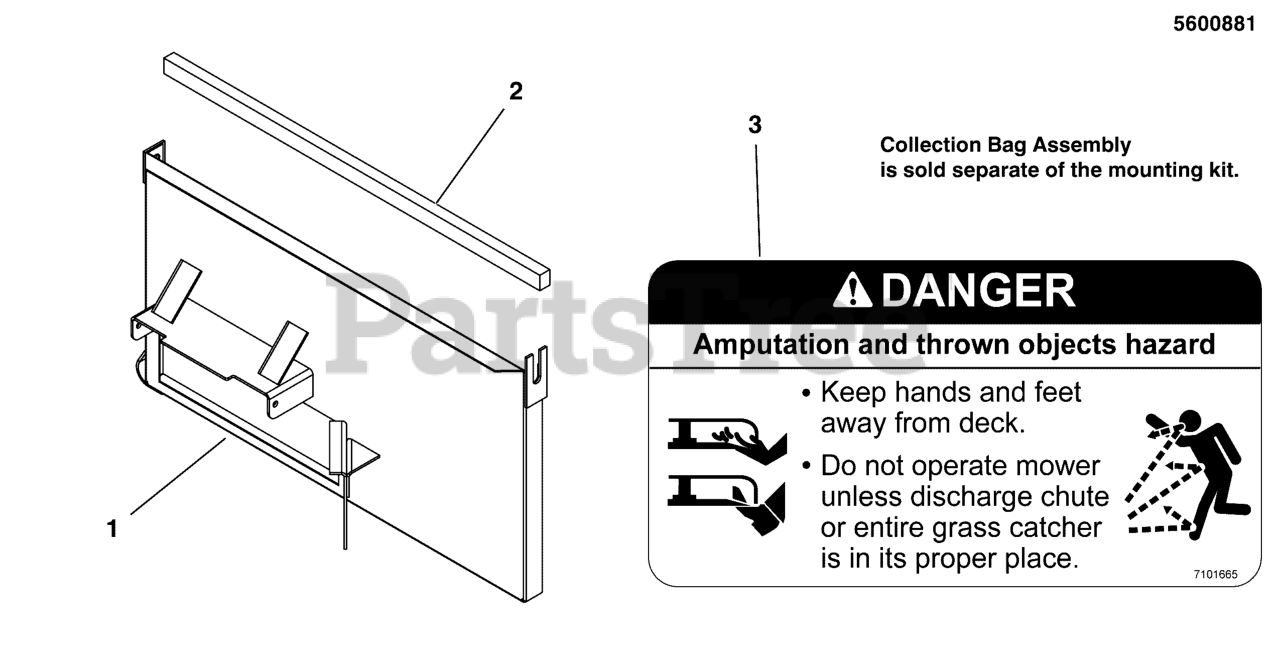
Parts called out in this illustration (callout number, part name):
1	WELD, BAGGER MOUNT -48 - BLACK
2	FOAM, 3/4 X 1 X 28.25
3	DECAL, DANGER DO NOT OPERATE W/O DEFLECT
